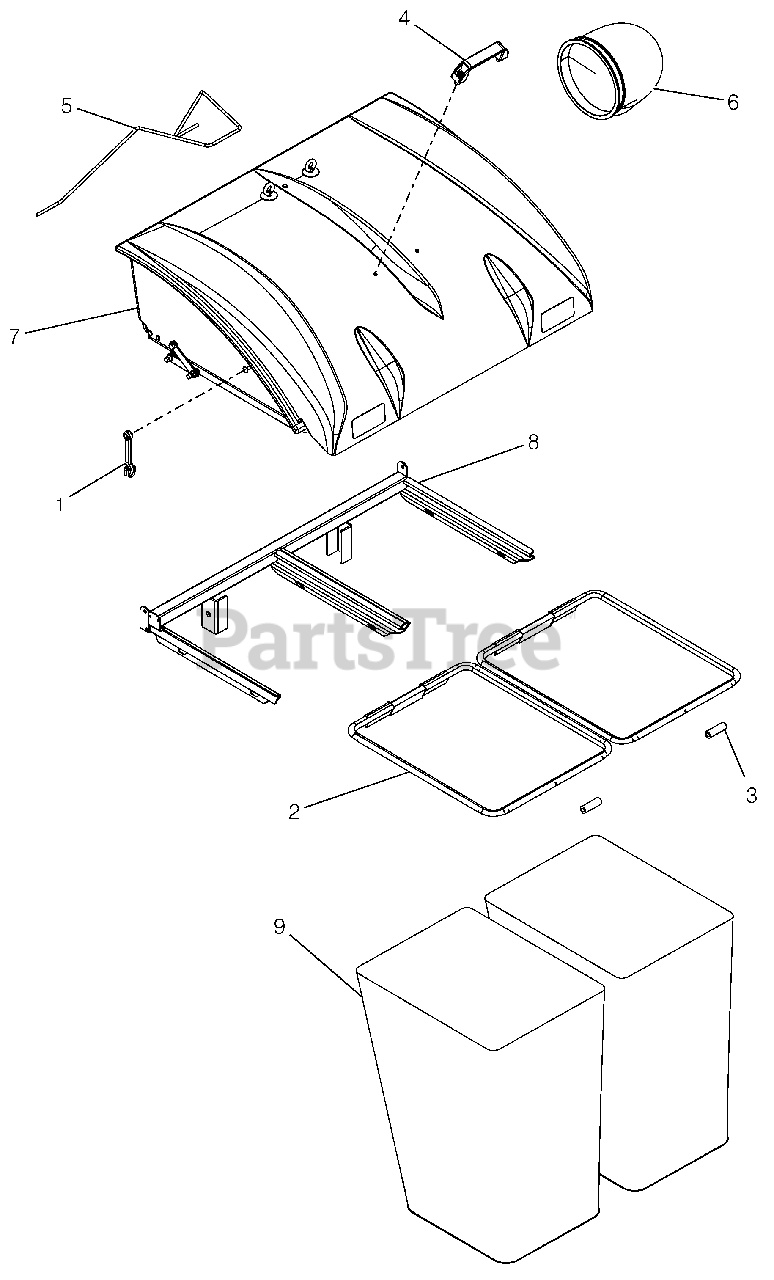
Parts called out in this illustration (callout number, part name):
1	RUBBER HOOD STRAP
2	BAG WIREFORM
3	RUBBER CONNECTOR - WIREFORM
5	ROPE, BAGGER RELEASE
6	ELBOW, PECO BAGGER
7	HOOD ASM PECO 2 BAG
8	FRAME ASM PECO 2 BAG
9	PECO BAGGER BAG
